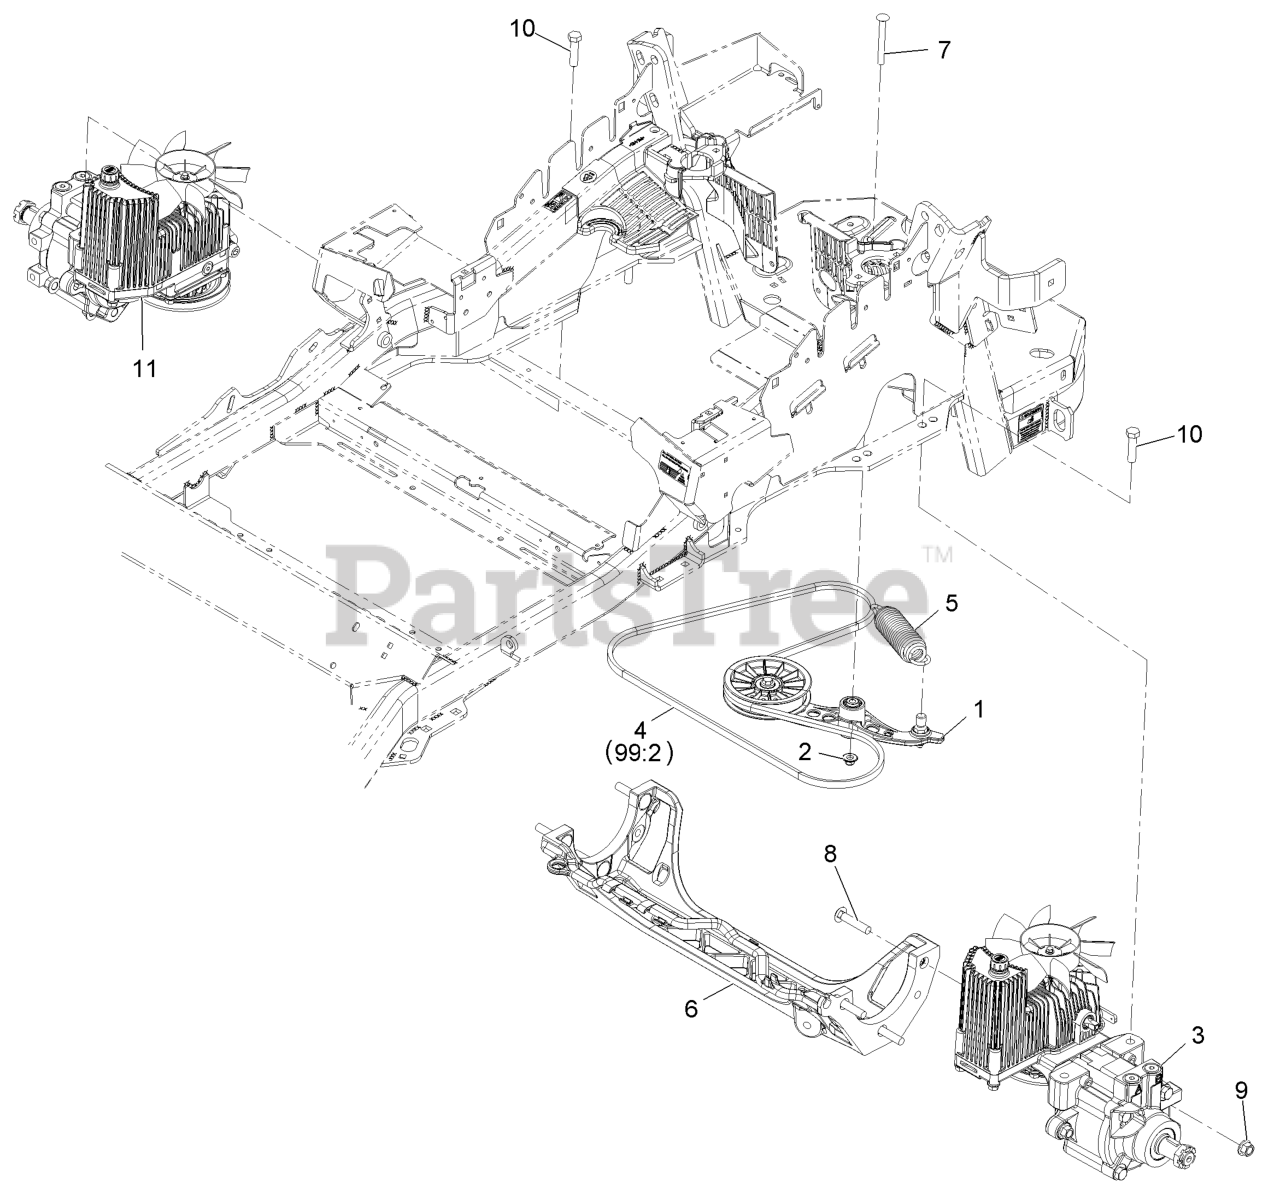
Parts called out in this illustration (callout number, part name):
1	PUMP IDLER ASM
2	Nut-Nyloc 3/8-16 Flg
4	BELT
5	SPRING-EXTENSION
7	BOLT-SHOULDER, CARRIAGE 3/8-16 X 3 1/2
8	SCREW-CARR
9	Nut-Lock 1/2-13
10	SCREW-HH
99:1	BOTTLE-OIL, 32OZ HYDRAULIC
99:2	BELT
